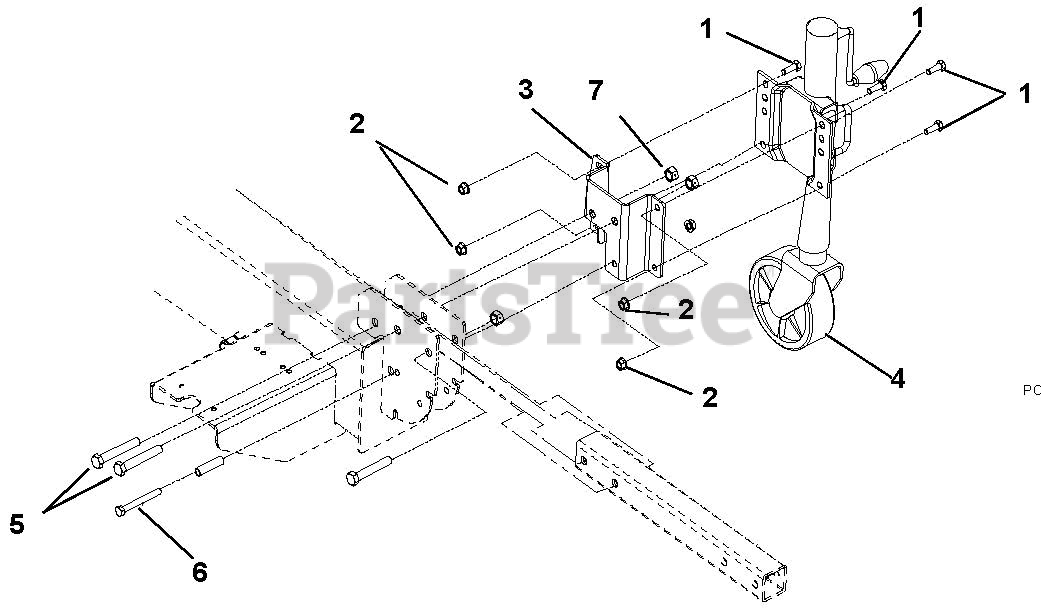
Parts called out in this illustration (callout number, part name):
1	Bolt, Hex .38-16 x 1.00 GR5
2	Nut, Top Flange Locking .38-16
3	Bracket, Mounting
4	Stand, Jack w/Wheel
5	Bolt, Hex .50-13 x 3.25 GR5
6	Bolt, Hex .38-16 x 3.25 GR5
7	Nut, Center Locking .50-13
